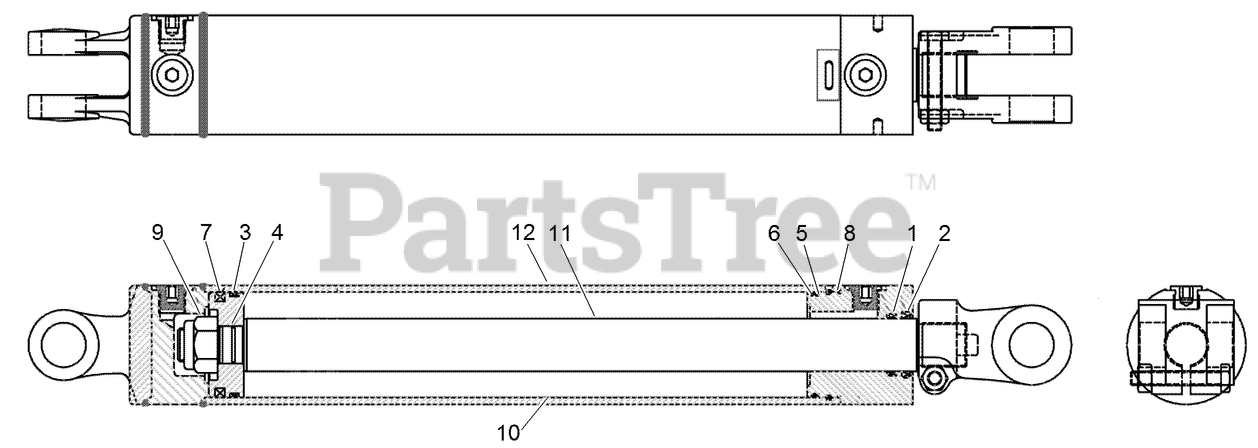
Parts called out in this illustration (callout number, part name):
1	SEAL-ROD
2	SEAL-WIPER
3	SEAL-Piston
4	O-RING
5	RING-BACKUP
6	O-RING
7	RING-WEAR, PISTON
8	O-RING
9	NUT-CYLINDER PISTON
10	PISTON-Cylinder
11	ROD-Piston
12	TUBE-Cylinder
13	GLAND-Cylinder End
15	SEAL KIT-Gland
